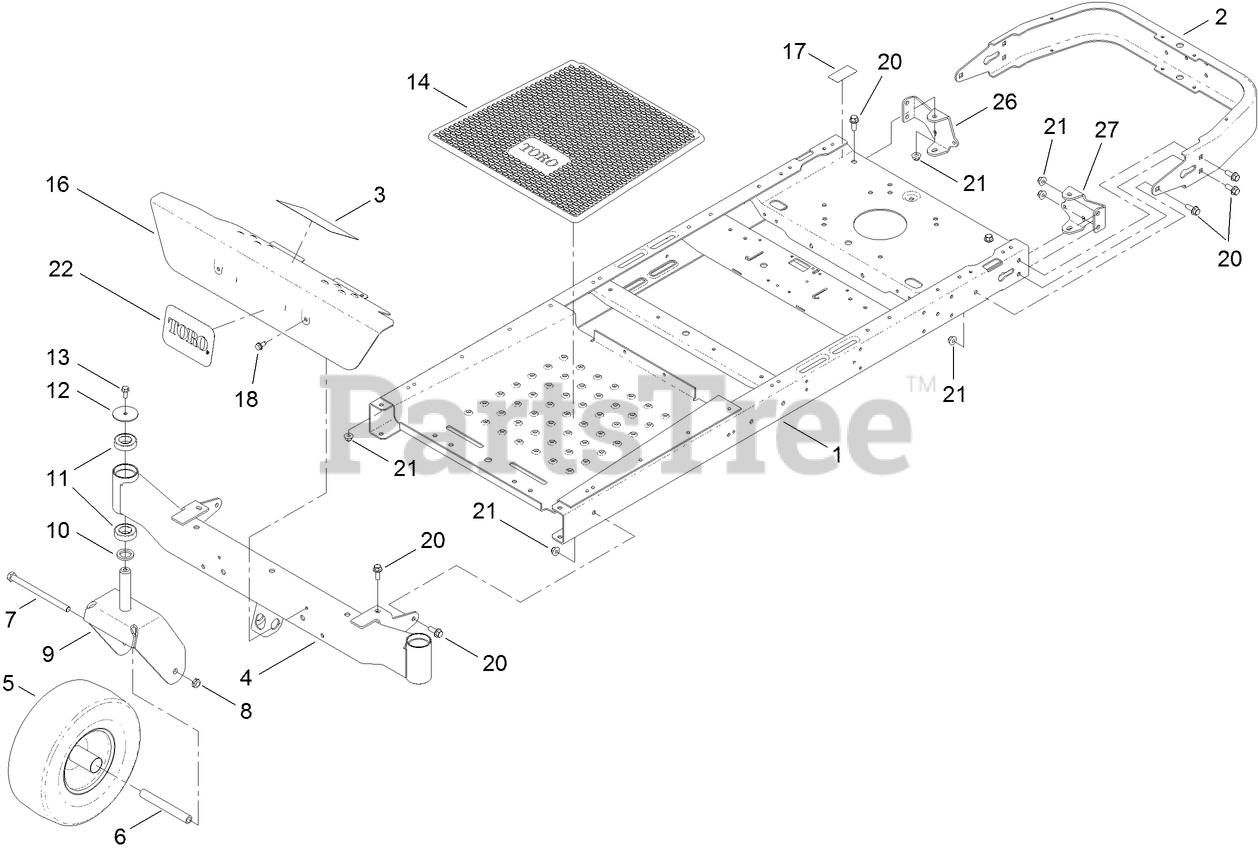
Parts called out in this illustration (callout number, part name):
2	BUMPER-REAR (WIDE)
4	AXLE-FRONT, WIDE
5	13 INCH WHEEL AND TIRE ASM
6	SPANNER
7	SCREW-HH
8	NUT-HEX
9	FORK-CASTER
10	WASHER-THRUST
11	BEARING-BALL
12	WASHER
13	SCREW-HHF
17	DECAL-BYPASS
18	SCREW-HWHTF
20	SCREW-HHF
21	NUT-HF, NI
22	DECAL
26	MOUNT-HYDRO, REAR (RH)
27	MOUNT-HYDRO, REAR (LH)
